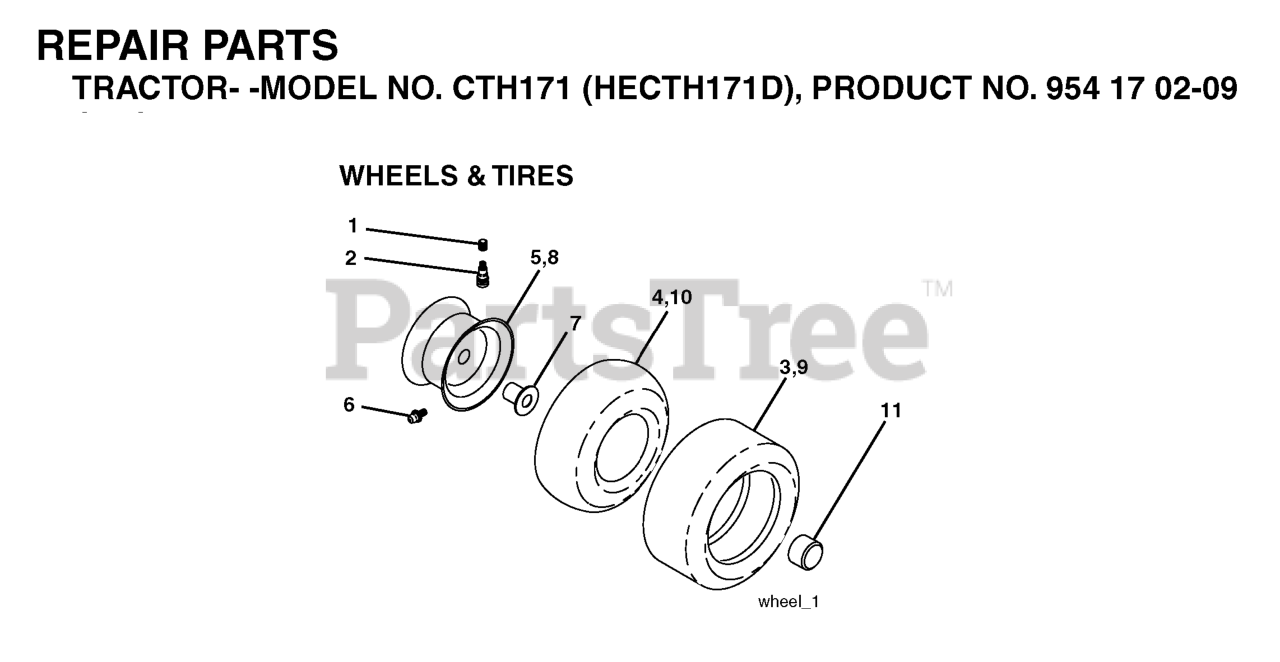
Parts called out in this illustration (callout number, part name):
2	VALVE STEM LT
3	TIRE HEAVY DUTY
4	TUBE.5.3/4.5/6
5	RIM ASM 6" FRONT SILVER
6	FITTING LT
7	BEARING T
8	RIM ASM 8" REAR SILVER
9	TIRE.TS.20X10-8
10	TUBE
11	CAP, AXLE BLK
